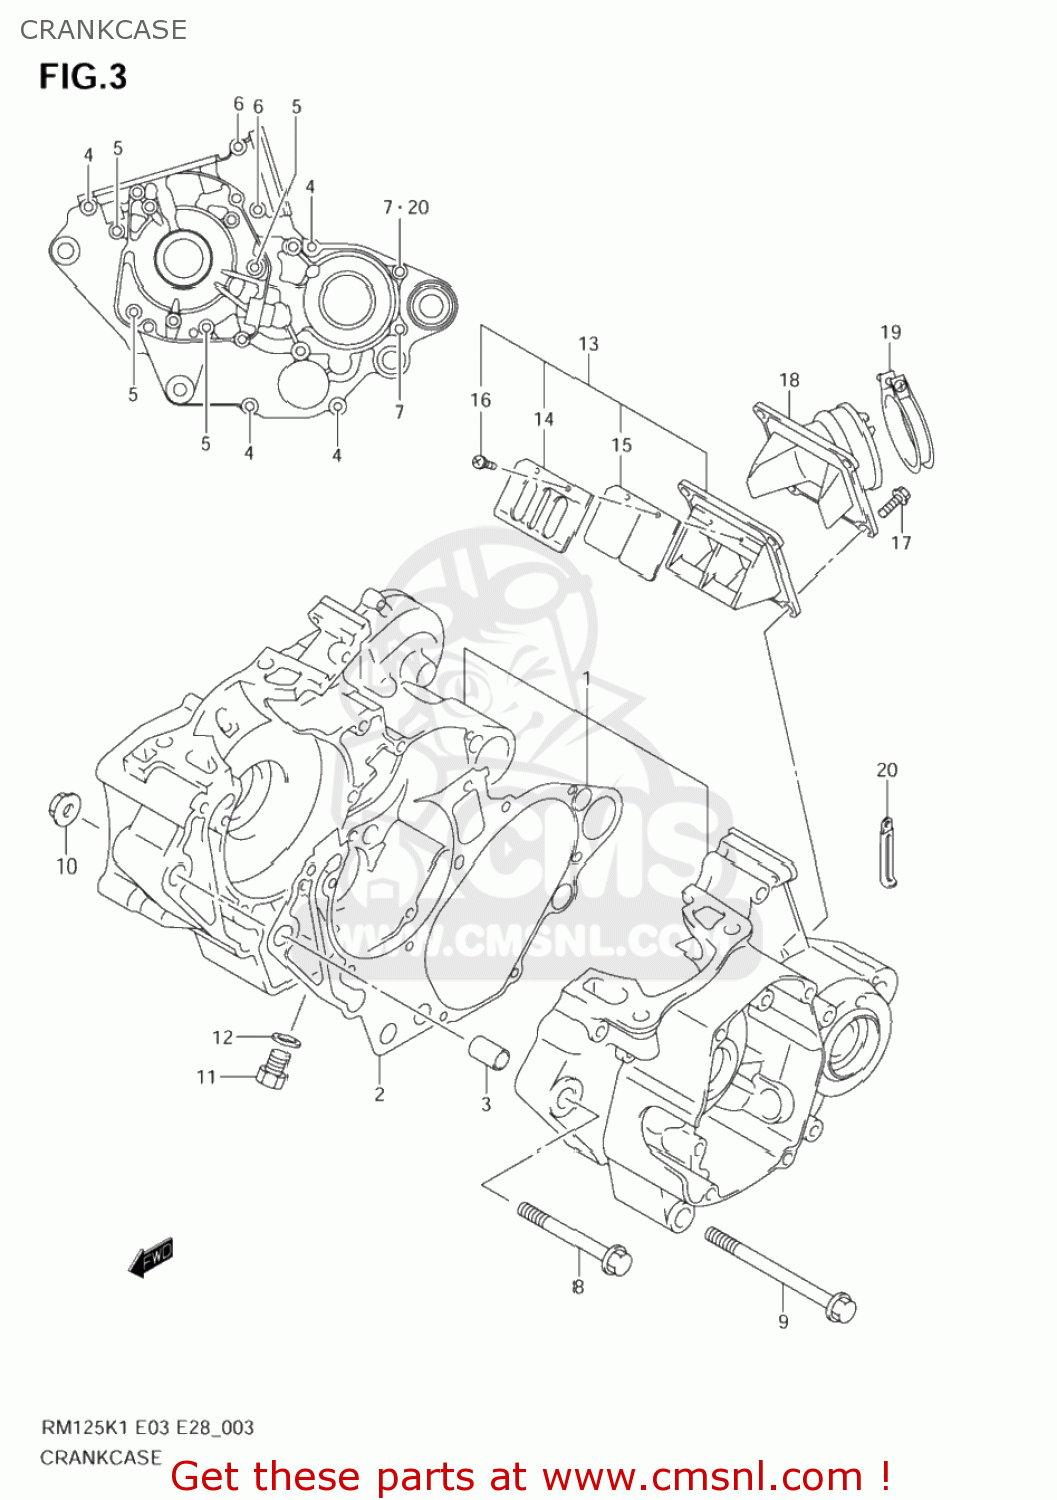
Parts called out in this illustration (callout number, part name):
1	CRANKCASE SET
2	GASKET,CRANKCASE (NAS)
3	PIN(13X10.4X20)
4	BOLT(6X40)
5	BOLT(6X45)
6	BOLT(6X50)
7	BOLT(6X55)
8	BOLT(10X90)
9	BOLT(10X130)
10	NUT
11	Bolt
12	GASKET(12.1X16.2X3.7) (NAS)
13	VALVE ASSY,REED
14	STOPPER,REED VALVE
15	VALVE,REED
16	SCREW
17	SCREW
18	PIPE,INTAKE
19	CLAMP
20	CLAMP(L:80)
